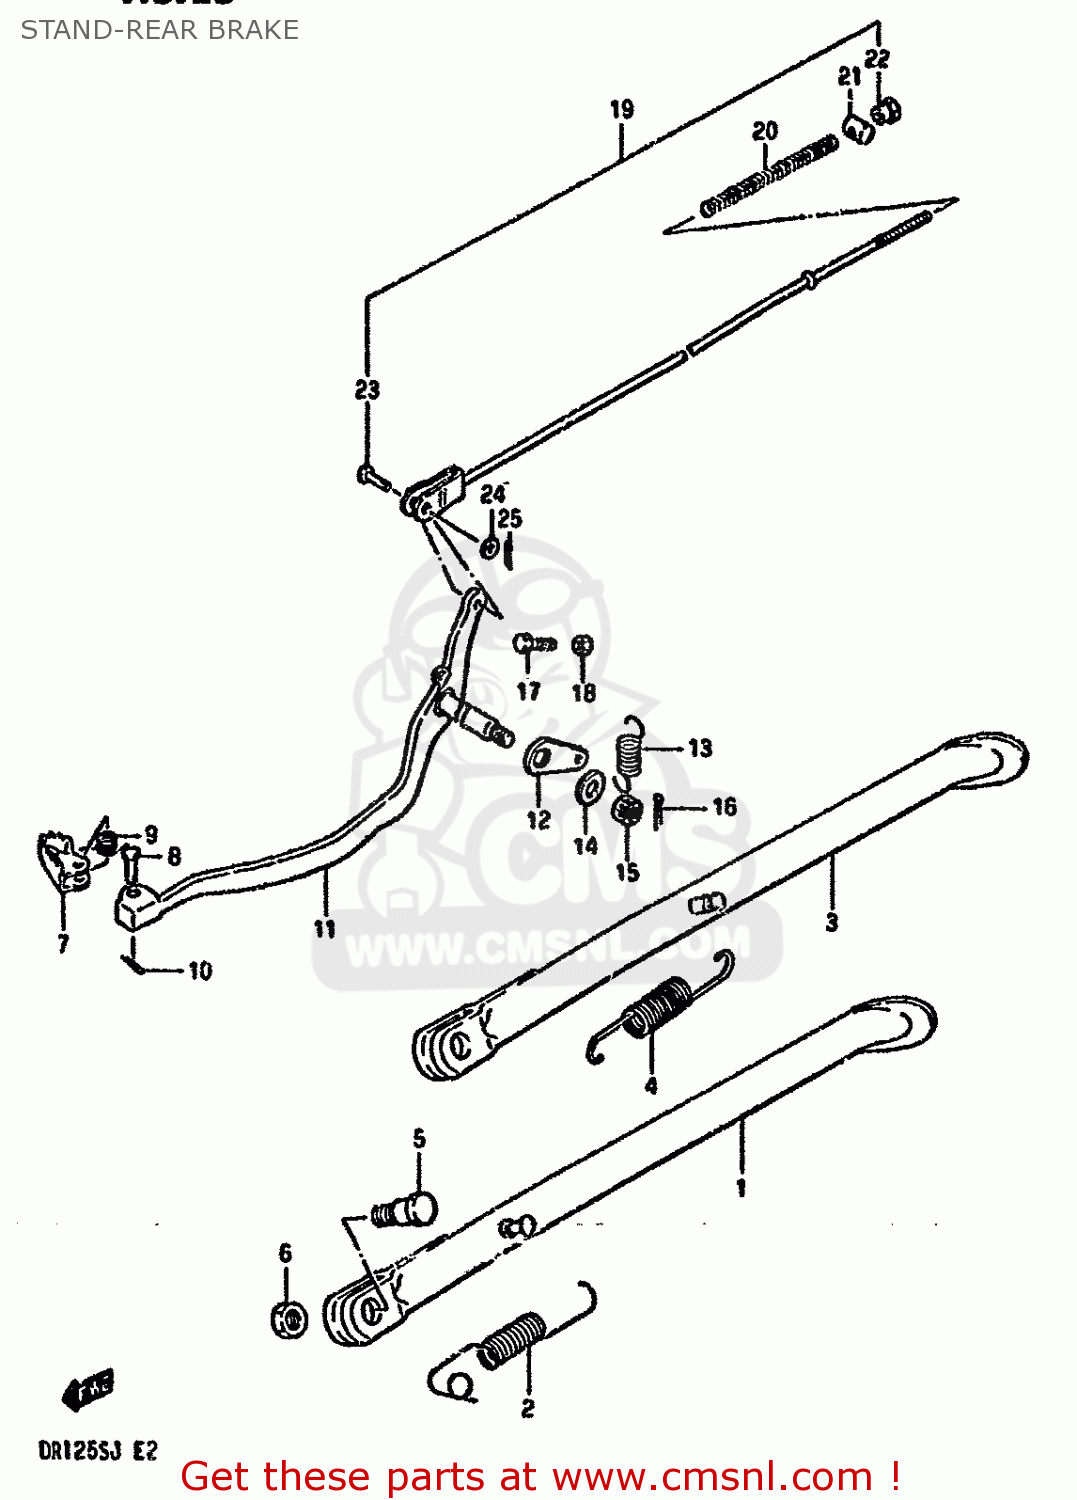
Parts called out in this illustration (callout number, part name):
1	STAND,PROP
2	SPRING
3	STAND, PROP (BLACK)
4	SPRING
5	BOLT L:30
6	NUT
7	PEDAL,BRAKE
8	PIN
9	SPRING
10	PIN
11	ARM,BRAKE PEDAL
12	ARM,BRAKE RETURN SPRING
13	SPRING
14	WASHER
15	NUT 8MM
16	PIN 20X20
17	BOLT(6X23)
18	NUT 6MM
19	ROD ASSEMBLY,REAR BRAKE
20	SPRING
21	PIN
22	NUT (6MM)
23	PIN(L:13.5)
24	WASHER
25	PIN 20X20
